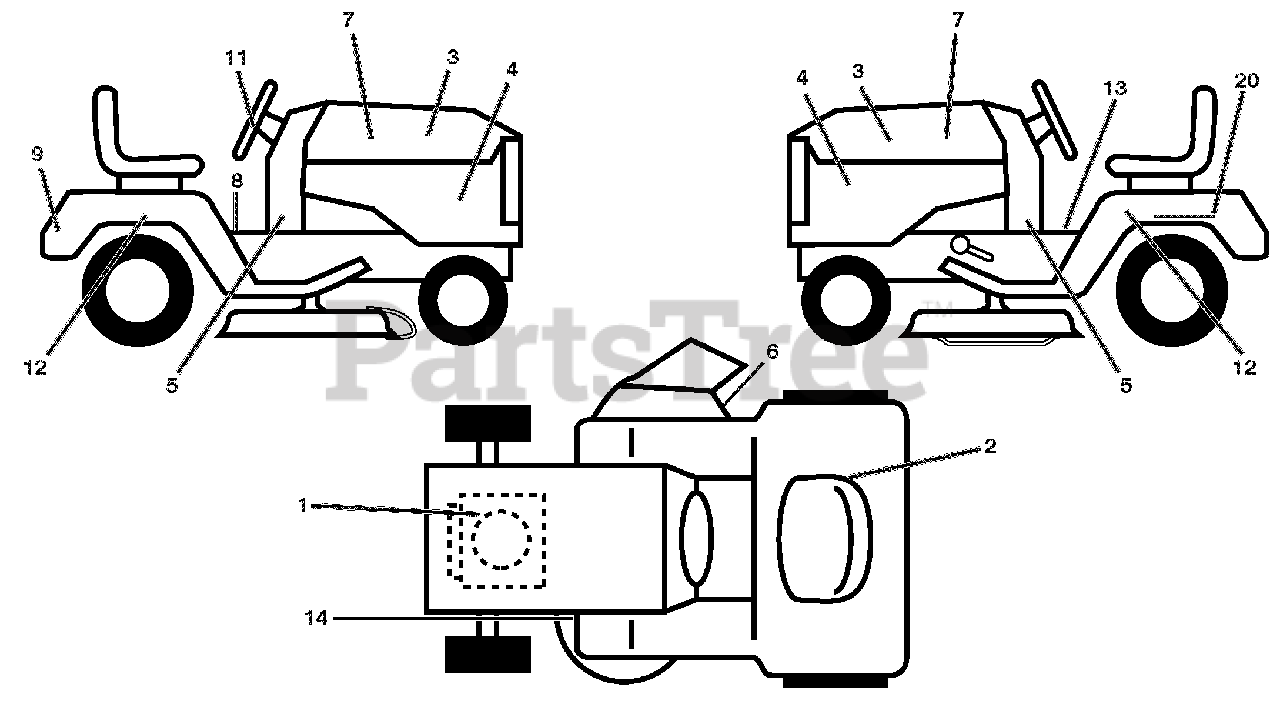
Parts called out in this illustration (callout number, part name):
1	DECAL ENGINE H.P.
2	Decal Fender Service
3	DECAL.HOOD.LH/RH.
4	DECAL.SDPNL.PWRDBY B&S.ARIENS
5	DECAL.DASH.LWOWER.20HP.ARIENS
6	DECAL.MOWER.WARN.KEEP HAND AWY
7	DECAL.REPLACEMENT
8	DECAL.FENDER.WARNING.ENG/FR.07
9	Decal, Fender
11	DECAL.WHEEL.STEER.ARIENS
12	DECAL FENDER SIDE HYDRO ARIENS
13	DECAL.FENDER
14	DECAL.V-BELT.SCH.42/46"MEC/ELE
20	DECAL.BAT.DAN/POI P/L SYM.WPN
